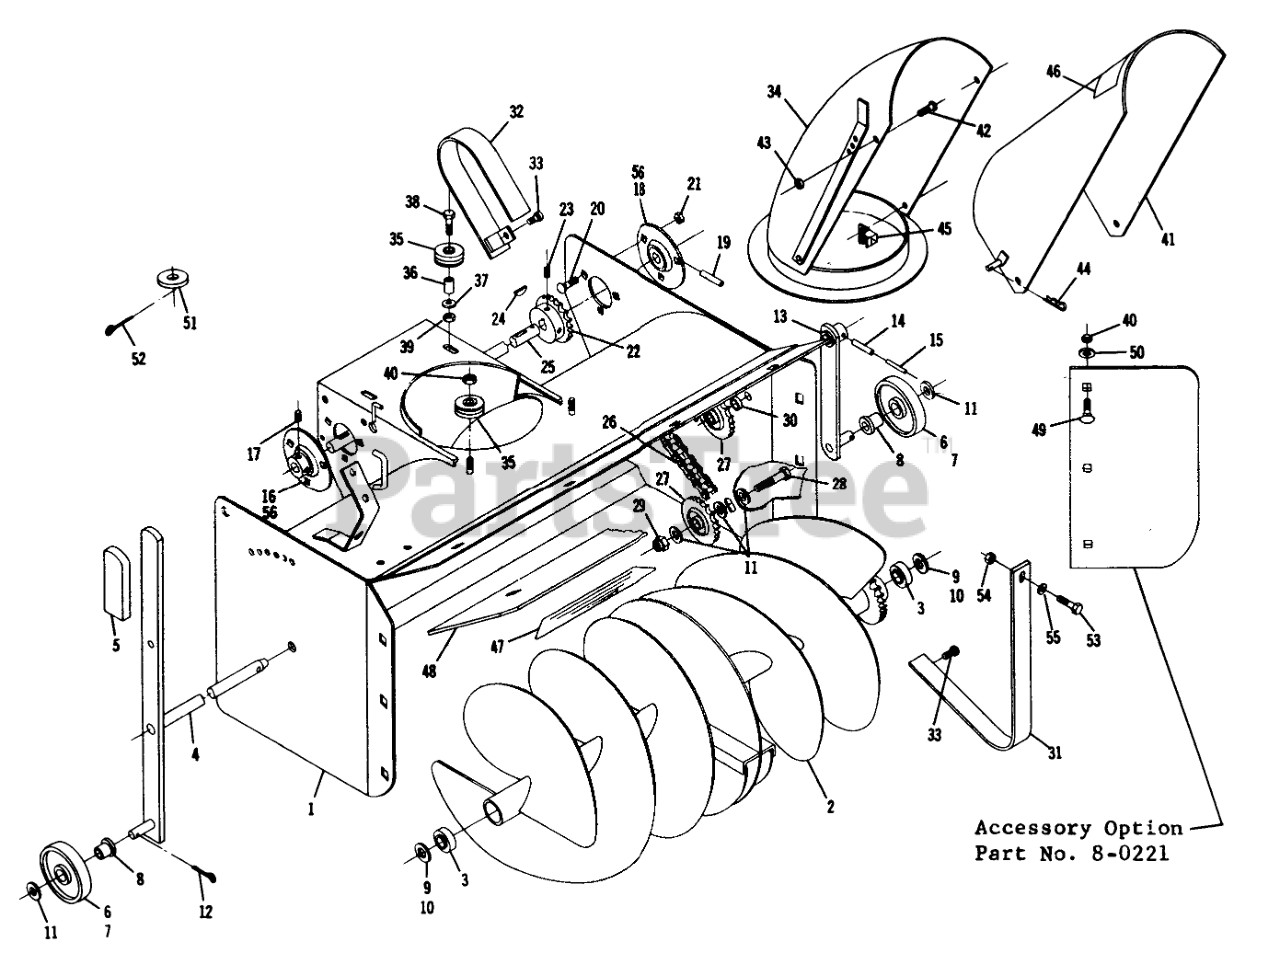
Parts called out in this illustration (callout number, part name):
1	Wrapper Ass-y
2	Auger
3	Ball
4	ASSY AUGER SHAFT R
5	GRIP
6	WHEEL BUSHING ASSY R
7	Wheel
8	Bushing
9	Washer
10	WASHER
11	Washer
12	Cotter Pin
13	Wheel Support
14	ROLL PIN 1/4 X 1-1/4
15	PIN-SPIROL
16	Ball Bearing-Self Aligning
17	Set Screw
18	Ball Bearing
19	PIN-ROLL, SPIROL
20	Bolt Hex 5/16-18 x 3/4
21	Nut-Nylok
22	SPROCKET
23	Set Screw Nylok
24	Key
25	Shaft-Drive
26	CHAIN
27	Idler Sprocket
28	Bolt-1/2-13-1 3/4
29	Locknut-1/2-13
30	SPACER
31	Guard-Inner
32	Guard-Outer
33	SCREW
34	S/A SHROUD R
35	Roller
36	SPACER
37	Washer
38	Bolt 1/4 20 x 1 1/4
39	Nut-Nylok
40	3/8-16 E.S.
41	Deflector
42	Bolt Pan Head 1/4-20 x 1/2
43	Nut, 1/4-20
44	Hairpin
45	CLAMP
46	Decal-Caution
47	Decal
48	Plate
49	Bolt 3/8-16 x 1
50	Washer
51	Washer, 5/8
52	Cotter Pin 3/16 x 1
53	Bolt-1/4-20 x 5/8
54	Nut 1/4-20 Keps
55	Washer
56	FLANGE
